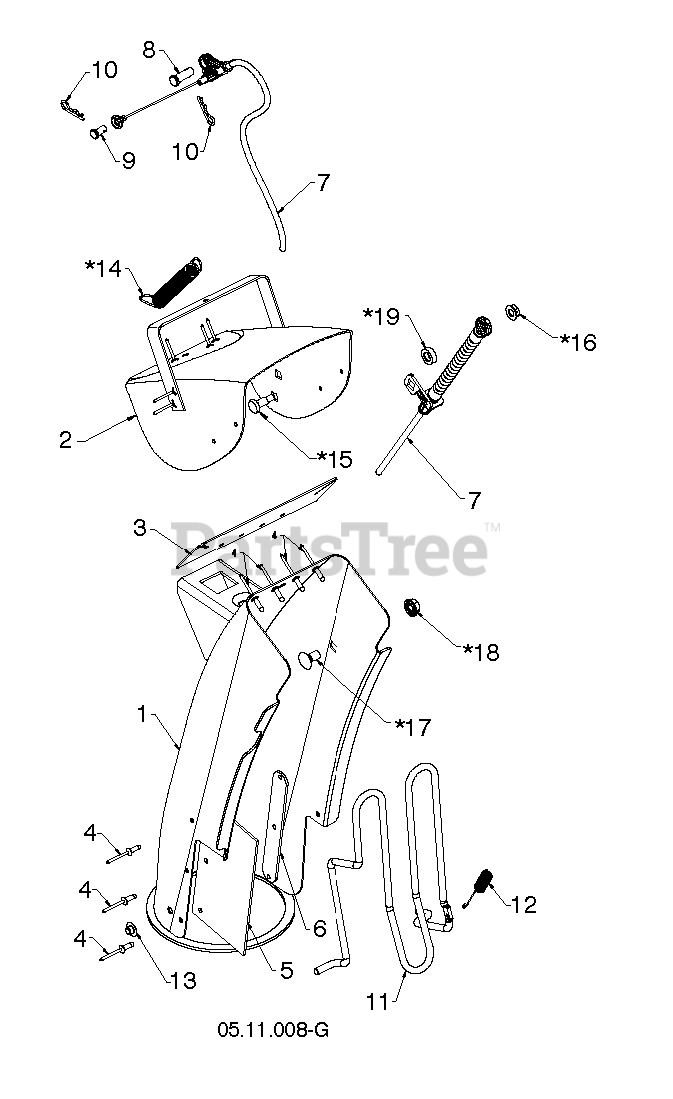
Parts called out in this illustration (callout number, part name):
1	ASM.CHUTE/DEFLECTOR.668
7	CABLE.CONTROL.CHUTE.DEFLEC
8	PIN CLEVIS 5/16X.875
9	PIN CLEVIS .25 X .31
10	HAIRPIN.SOFT.ZINC.059X1.125
11	ROD.GUARD.CHUTE (2 2)
12	SPRING.CHUTE.GUARD
13	NUT
